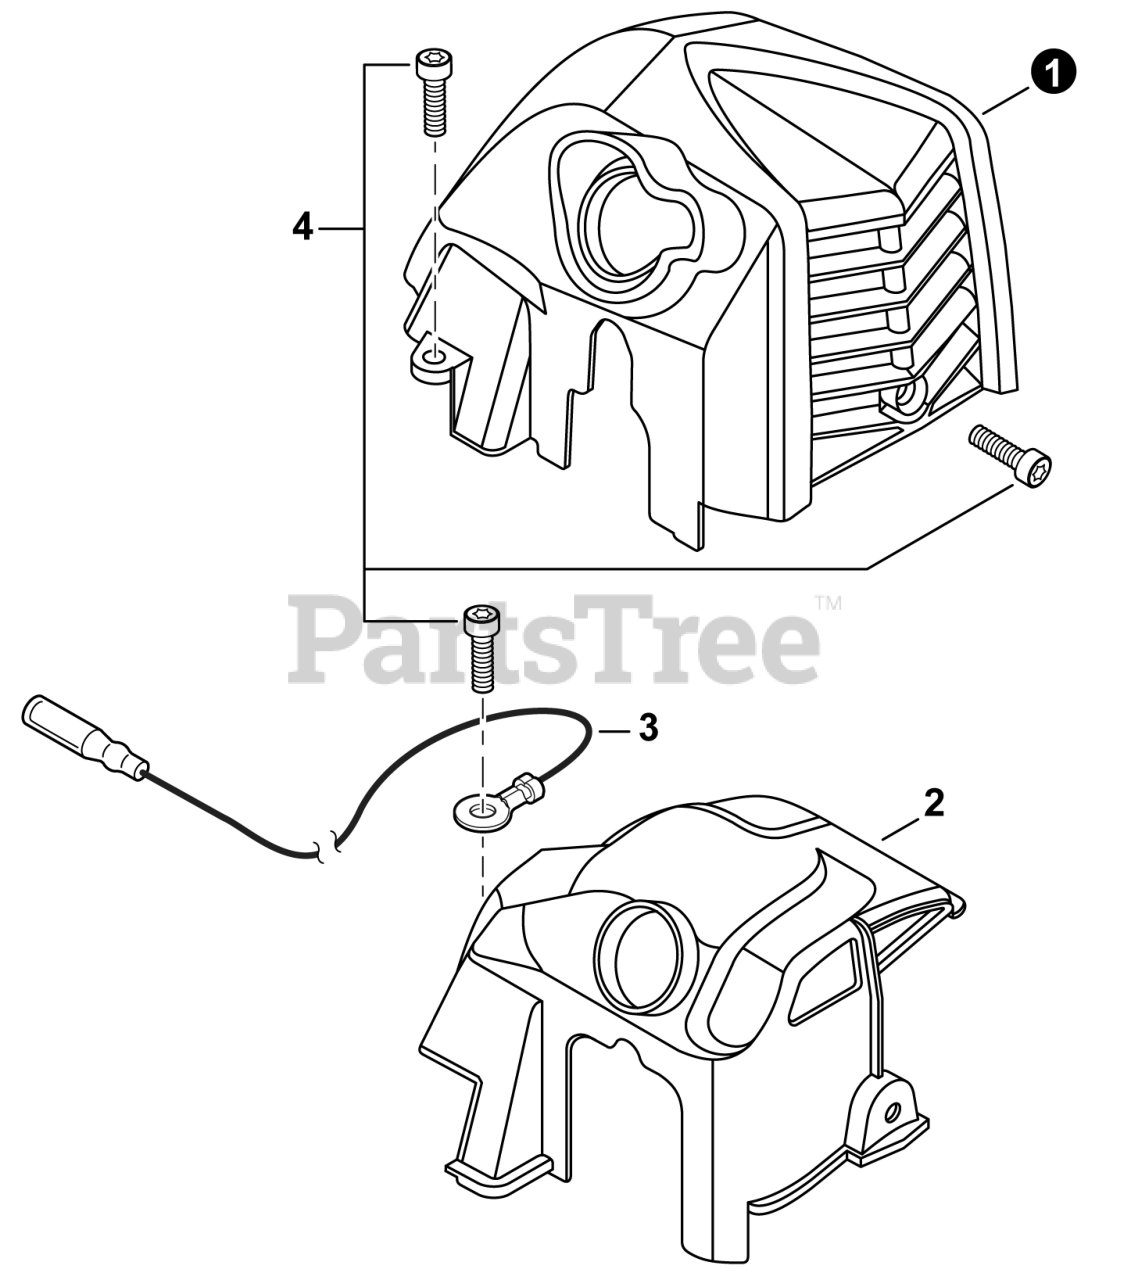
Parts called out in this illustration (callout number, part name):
1	COVER, ENGINE
2	COVER, CYLINDER
4	BOLT, TORX 5×12
